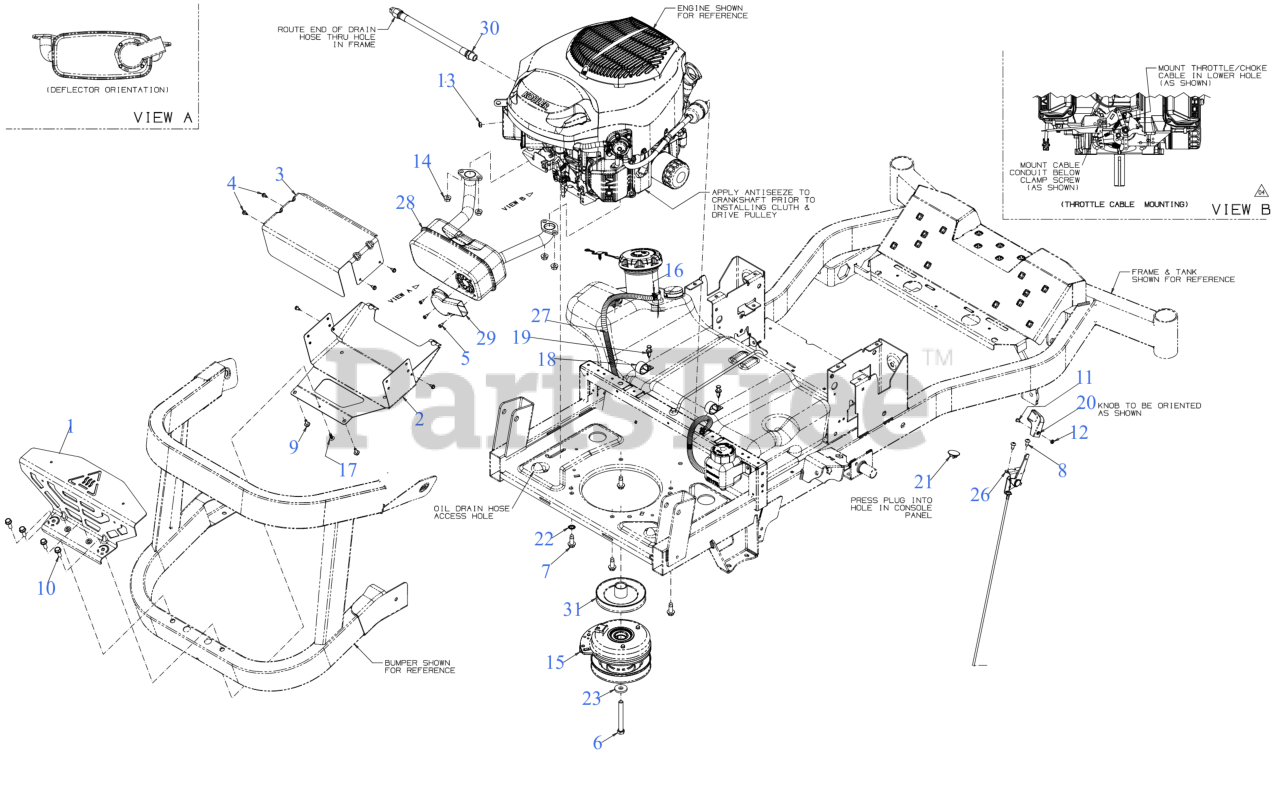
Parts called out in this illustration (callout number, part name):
1	MUFFLER COVER (REAR) (BLACK)
2	MUFFLER SHIELD (LOWER)
3	MUFFLER SHIELD (TOP)
4	HEX SCREW AB-TAP #10 x .50
5	HEX SCREW WASHER HD #8-18 x 0.500
6	SCREW 7/16-20 x 3.5 GR5
7	SCREW 3/8-16 x 1
8	SCREW 1/4-20 x .5
9	SCREW M6-1 x .625
10	SCREW 5/16-18 x .875 GR5
11	SCREW #8-32X.38 LG
12	HEX NUT 8-32
13	HEX NUT 1/4-20
14	HEX FLANGE NUT M8X
15	ELECTRIC PTO CLUTCH
16	HOSE CLAMP 1/20
17	RATCHET CLIP (.188 x .85)
18	CLAMP 1.00 DIA x .625
19	PLASTIC RIVET
20	THROTTLE CONTROL KNOB
21	CHOKE PLUG
22	LOCK WASHER 3/8
23	FLAT WASHER .445 x 1.248 x .170
26	THROTTLE CHOKE CABLE 51.0 LG
27	FUEL HOSE LOW PERMEATION 36"
28	EXHAUST MUFFLER (KH TWIN)
29	EXHAUST DELECTOR (LONG)
30	OIL DRAIN HOSE (11.26" 3/8 NPT)
31	TRANSMISSION DRIVE PULLEY
